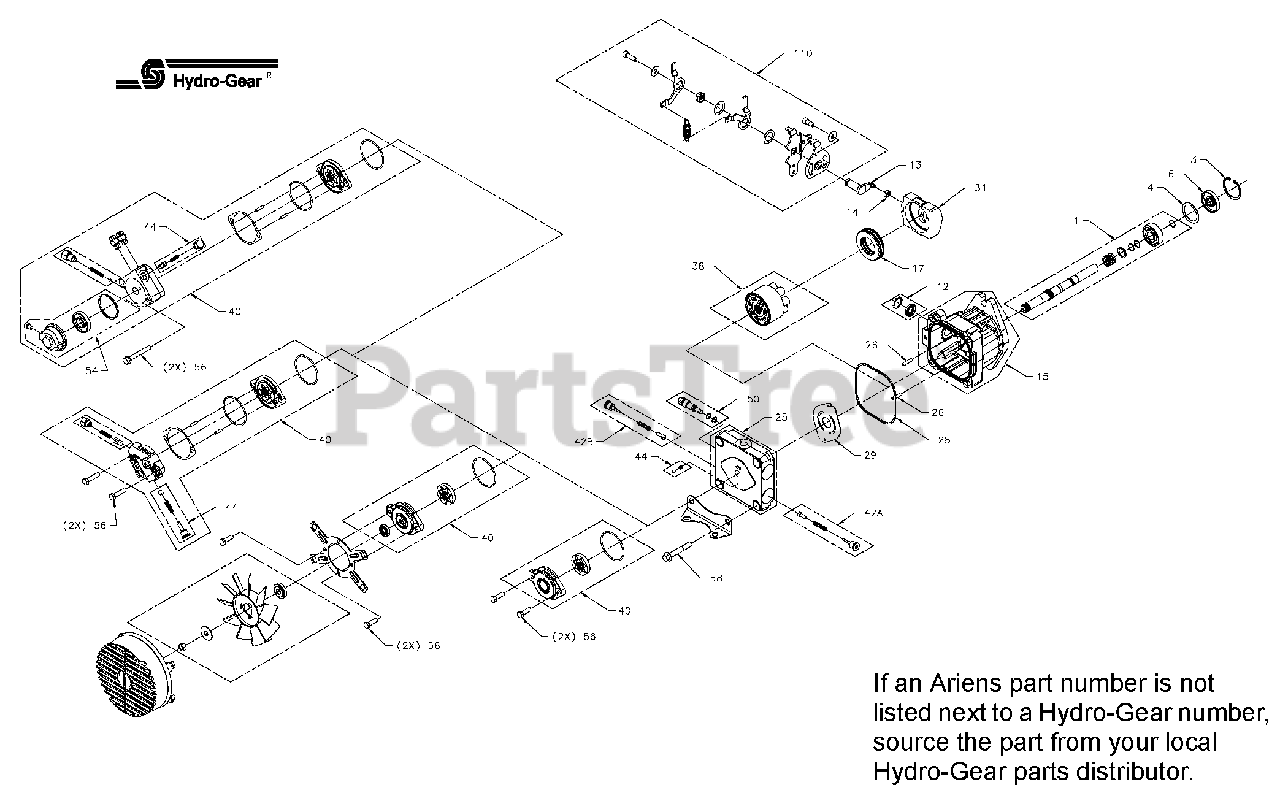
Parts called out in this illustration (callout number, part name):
1	Kit, Pump Shaft
3	Ring, Ret 47 Int
4	Washer, 1.45 x 1.84 x .04
6	Seal, Lip 17 x 47 x 8
12	Kit, BDP-16A Trunnion Seal
13	Arm, Trunnion
14	Guide, Slot
15	Service Kit, Housing
17	Bearing, Thrust Ball 42 x 68 x 16
25	Kit, End Cap
26	Pin, .219 x 1
28	O-Ring, Sq .1 x (4.3 x 4.6)
29	Valve Plate
31	Plate, Swash 21cc
38	Kit, Motor Block
40	Kit, Aux Pump
42	Kit, Shock Valve 200 Bar
44	Kit, Chrg Relief Valve
50	Kit, Bypass Valve
54	Auxilarty Filter Kit
56	HFHCS 5/16-18 x 2.5
58	Kit, Bolt
NS	Kit, Rtn
